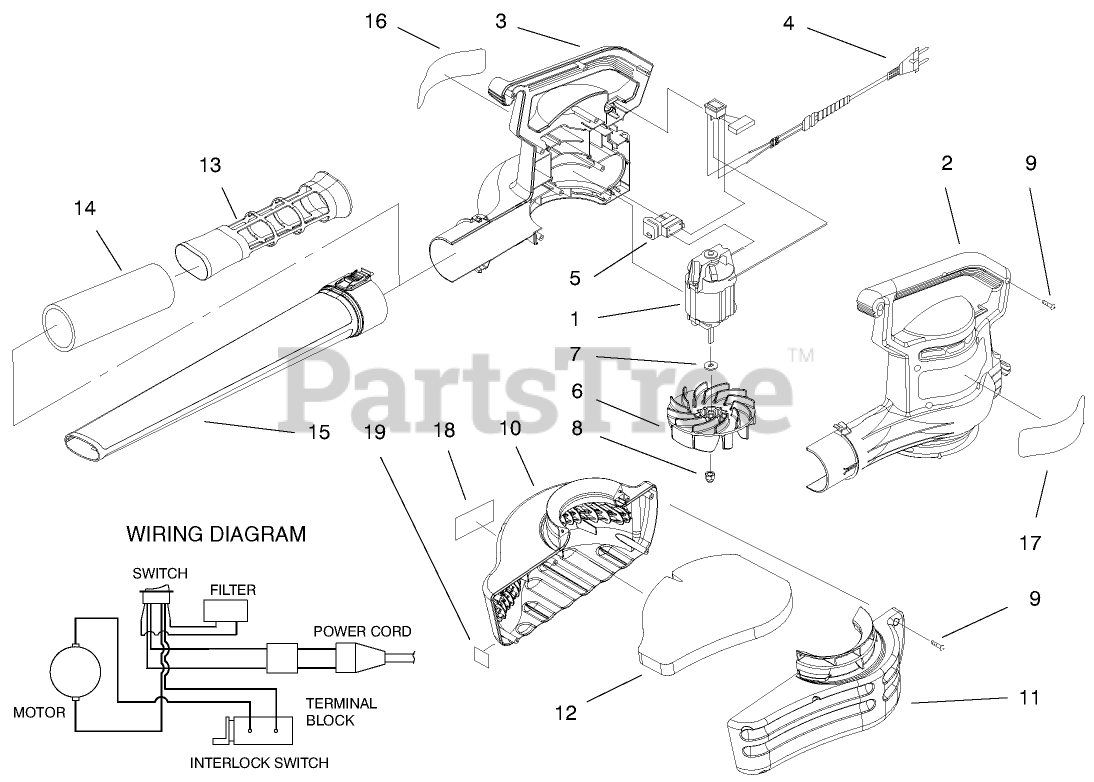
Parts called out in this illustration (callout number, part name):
1	MOTOR - 2.25" STACK 230V
3	HOUSING, RH - 230V BLOWER
4	WASHER-SPRING
7	WASHER-FLAT
9	SCREW-PPH
12	FOAM - INLET
13	INSERT - QUIET
